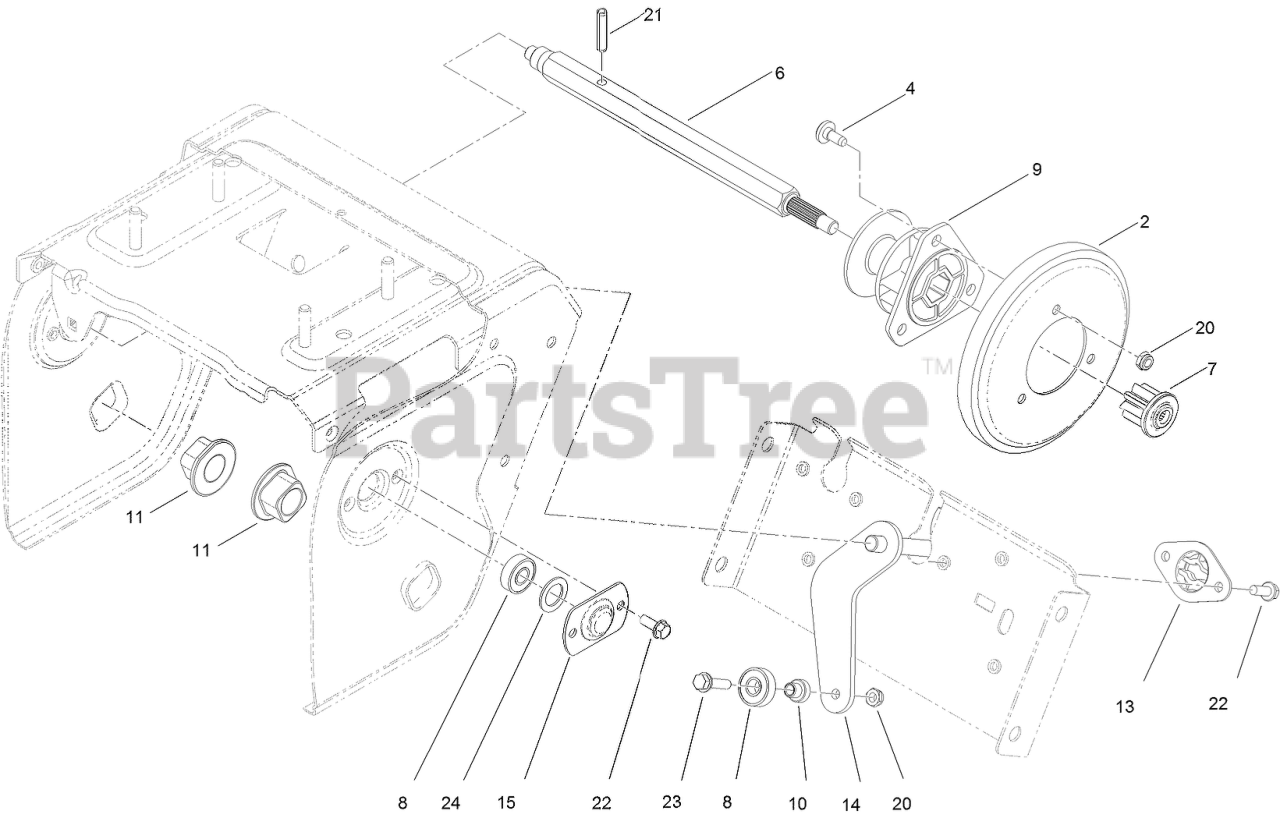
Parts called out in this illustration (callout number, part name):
2	WHEEL-FRICTION
4	SCREW-SHOULDER
6	SHAFT-HEX
7	GEAR-PINION, 8 TOOTH
8	BEARING-BALL
9	TRUNNION
10	SPACER-PLATE, SHIFT
11	BUSHING-AXLE
13	RETAINER-PLATE, SHIFT
14	SHIFT PLATE ASM
15	RETAINER-BEARING
20	NUT-LOCK, NI
21	PIN-ROLL, SLOTTED
22	SCREW-HWH
23	SCREW-HWHTF
24	WASHER-RUBBER
